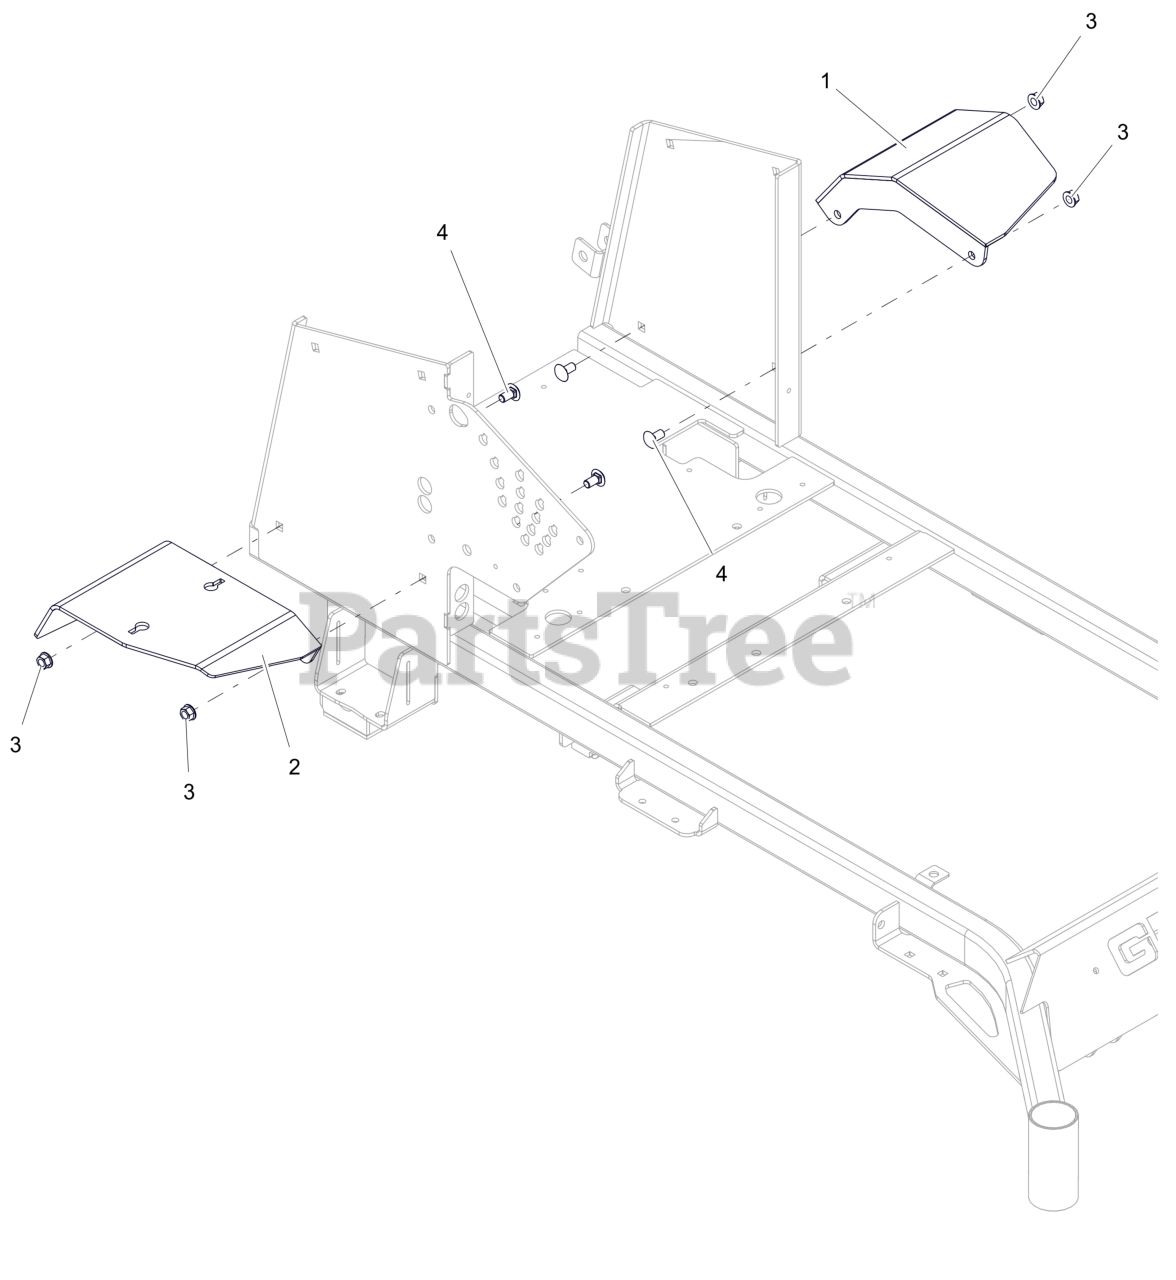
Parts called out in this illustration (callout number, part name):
1	WLDMT- LH FENDER (RED)
2	WLDMT-RH FNDR/BATTERY MTG(RED)
3	NUT-LK-CTR-FLG .375-16 GF ZCC
4	BLT, RHSSN .38-16X.75 G5 ZCC
